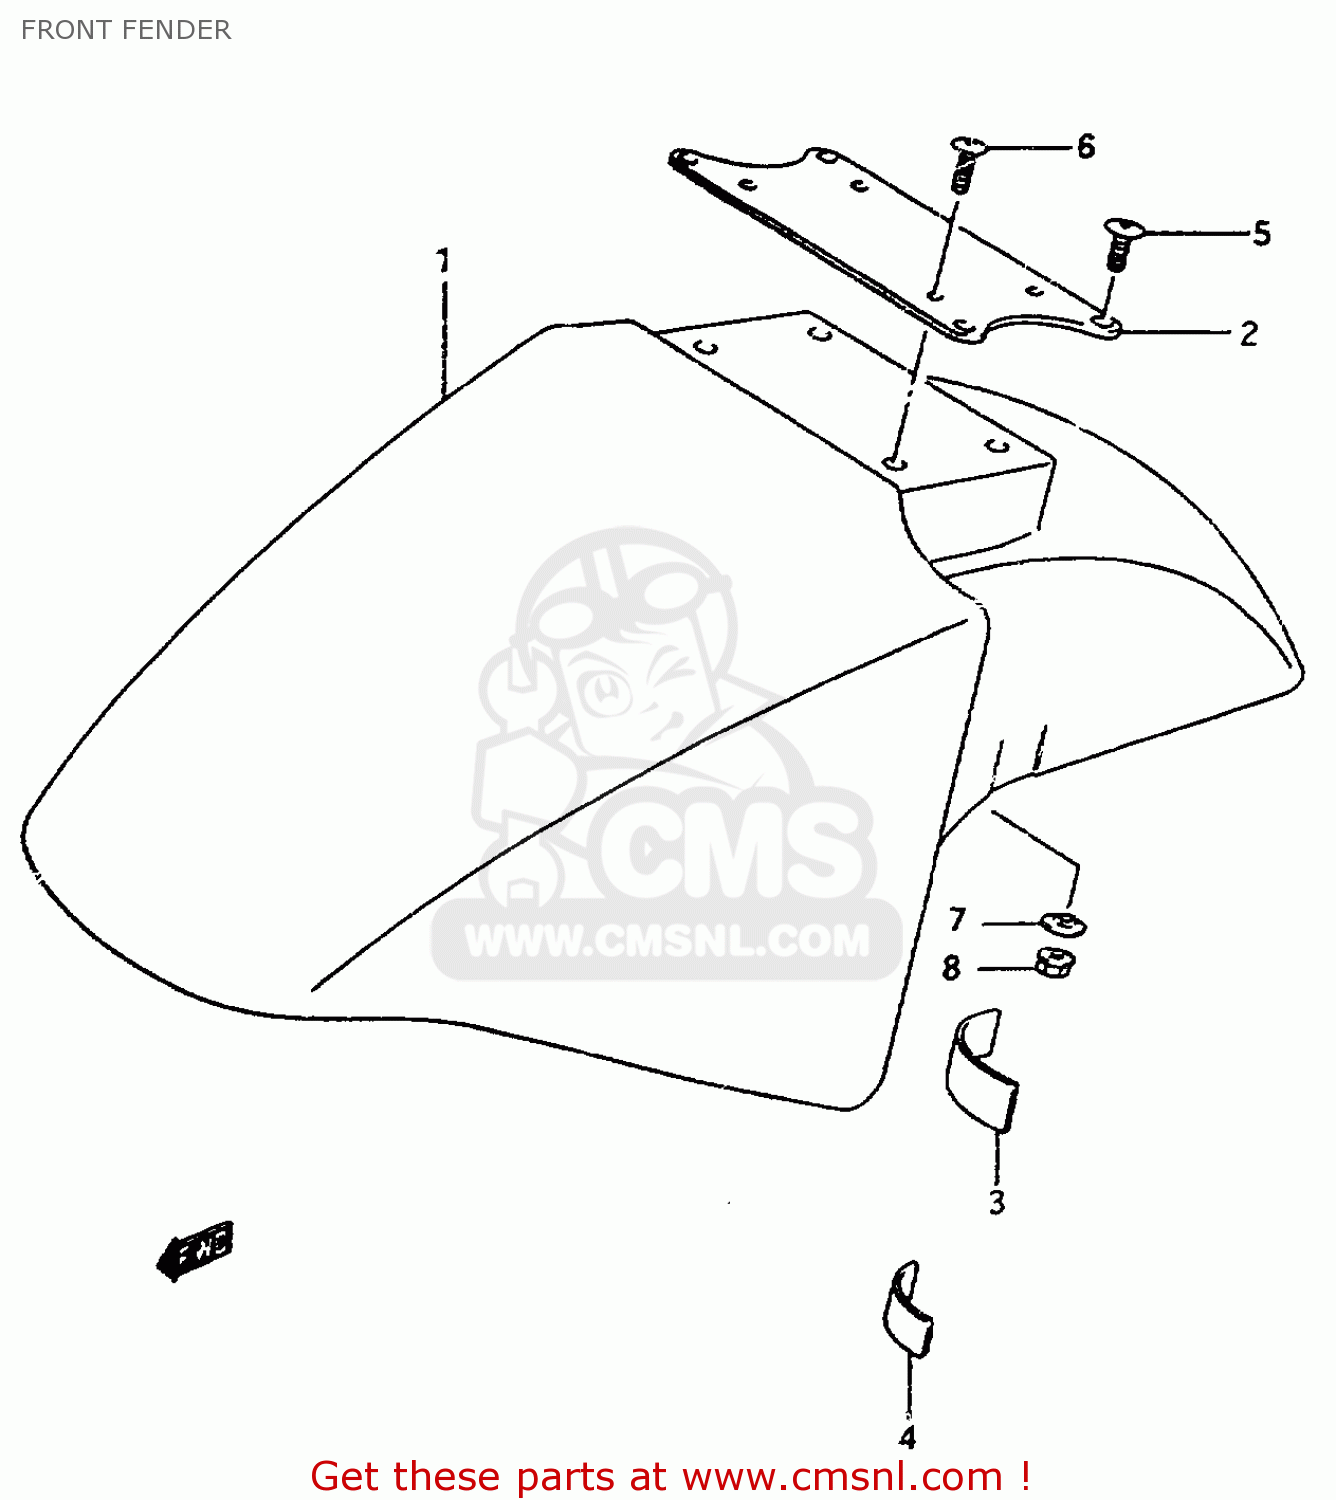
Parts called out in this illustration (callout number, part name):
1	FENDER,FR
2	BRACE,FR FENDER
3	CUSHION,FRONT FENDER
4	CUSHION
5	SCREW(6X12)
6	SCREW
7	WASHER
8	NUT
